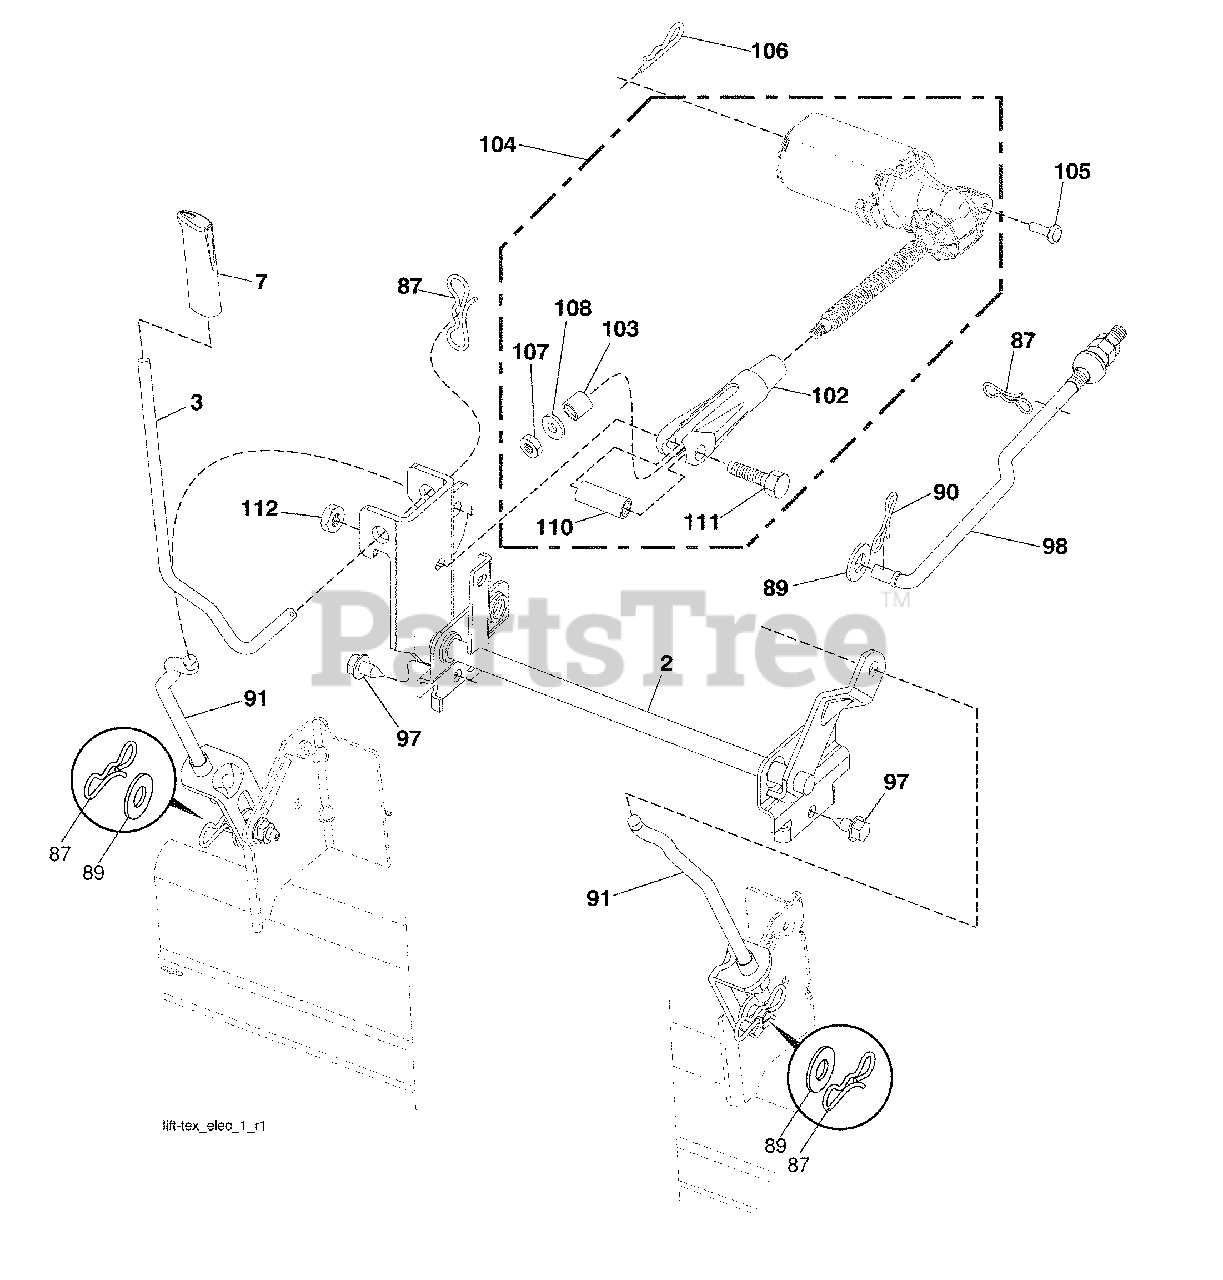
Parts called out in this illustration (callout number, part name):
2	Shaft Asm., Lift
3	Rod Indicator Lift Electric
7	Cap Indicator Lift Electric
87	Pin Cotter 7/16 Bow Tie Lock
89	Washer Clear Zinc
90	Pin Cotter 5/16 Bow Tie Lock
91	Link Asm. Lift Rear
97	Screw 3/8-16 x .75
98	Link Lift Susp. Front Mower
102	Clevis Motor Electric
103	Spacer Tubular
104	Actuator Decklift
105	Rivet Drilled 1/4 Dia.
106	Retainer Spring
108	Washer 9/32 x 5/8 x 16 Ga.
110	Spacer Clevis
111	Bolt Hex 5/16-18 x Gr. 5
112	Nut Lock Hex Flange 5/16-18
